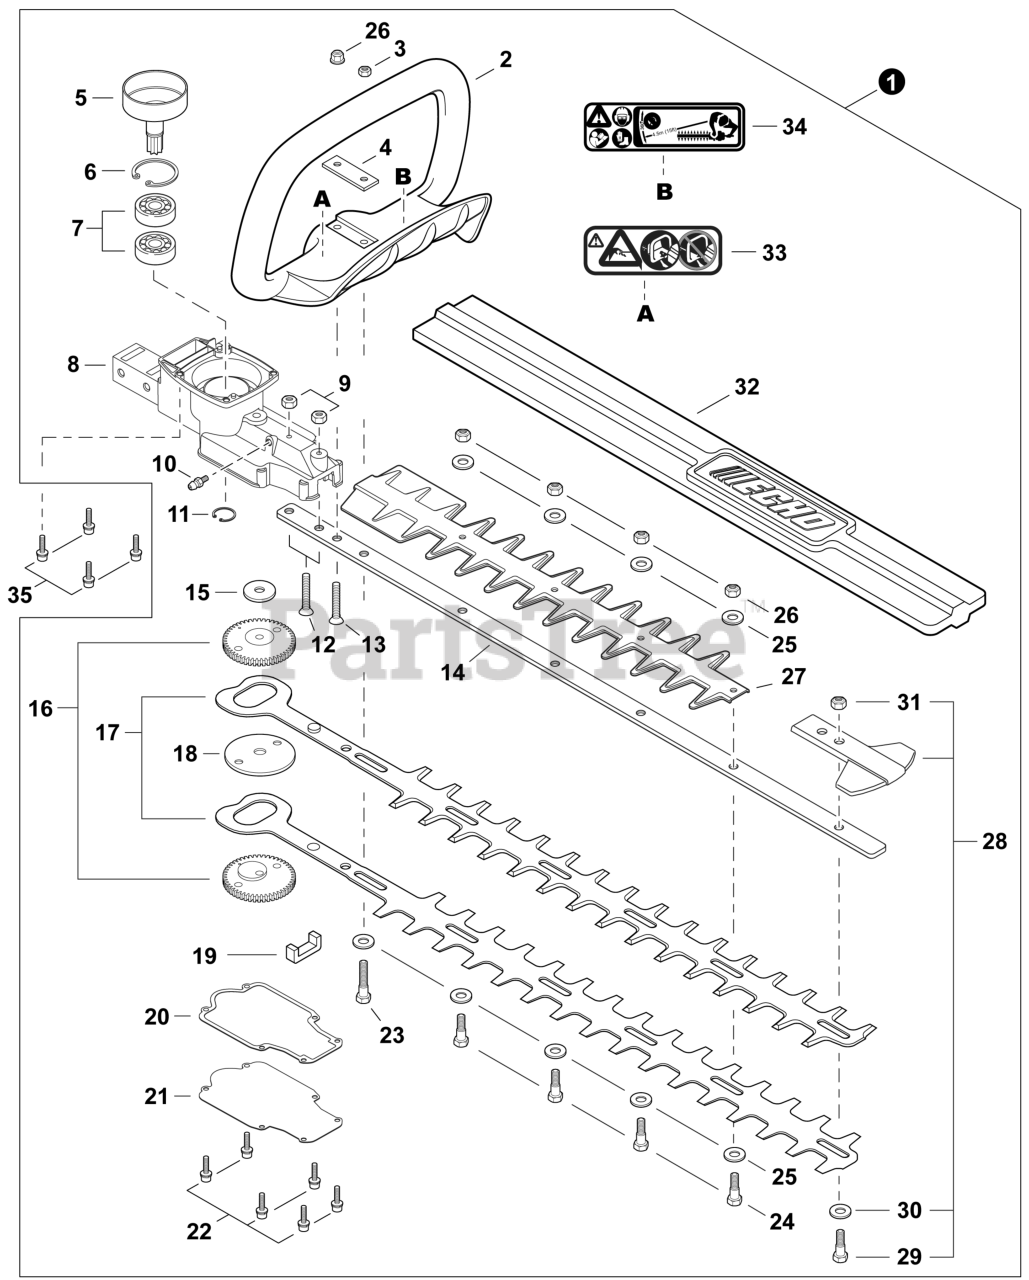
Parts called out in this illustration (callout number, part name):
1	CUTTING HEAD KIT
2	HANDLE, FRONT
3	NUT, FLANGE M5
4	PLATE, EYE
5	DRUM, CLUTCH
6	RING, SNAP 35
7	BEARING, BALL 6202
8	CASE, GEAR
9	NUT, HEX M6
10	FITTING, GREASE
11	RING, SNAP 14
12	SCREW 6×30
13	SCREW 5×30
14	SUPPORT, BLADE
15	WASHER 30
16	GEAR, SPUR
18	WASHER 50
20	GASKET, GEAR CASE
21	COVER, GEAR CASE
22	BOLT, TORX 4×12
23	BOLT M6×35
24	BOLT 6×18
25	WASHER 6.5×15.5×0.6
27	GUARD, CUTTER BLADE
28	TIP GUARD KIT
29	BOLT 6×18
30	WASHER 6.5×15.5×0.6
32	SCABBARD 24"
33	LABEL - CAUTION
34	LABEL - CAUTION - ISO
35	BOLT, TORX 4×16
